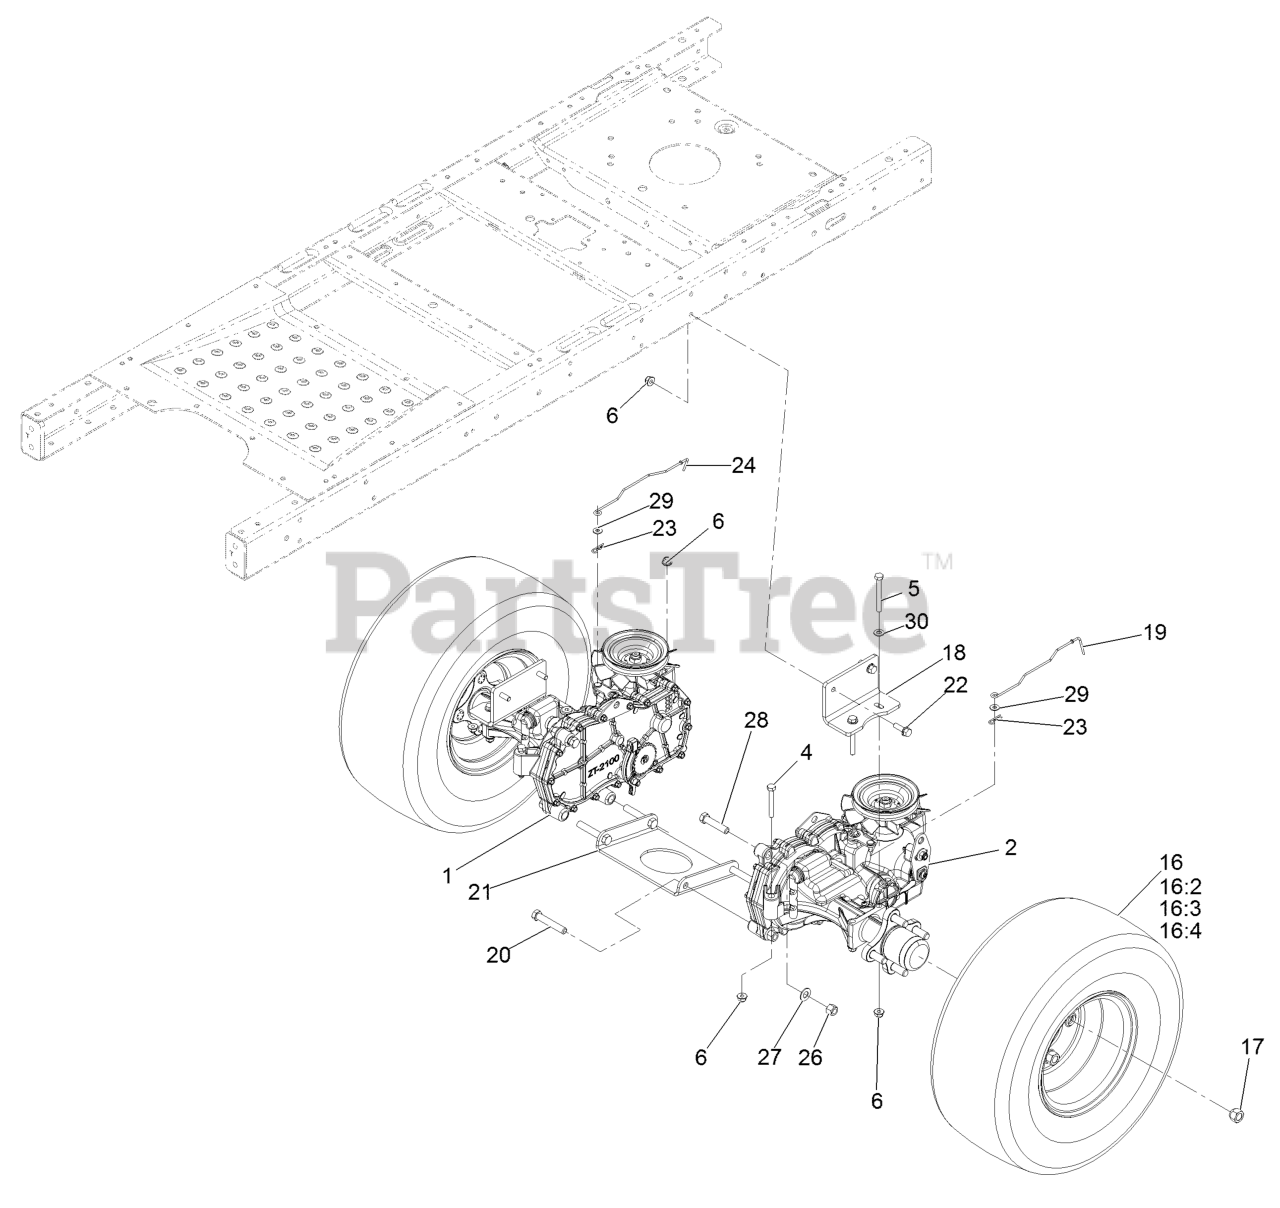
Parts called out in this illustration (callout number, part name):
1	RH HYDRO TRANSMISSION ASM
2	LH HYDRO TRANSMISSION ASM
4	SCREW-HH
5	SCREW-HH
6	NUT-HF, NI
16	2 PLY TIRE AND WHEEL ASM
16:2	TIRE-2 PLY
16:3	Stem-Valve
17	NUT-LUG
18	MOUNT-HYDRO
19	ROD-BYPASS, LH
20	SCREW-HH
21	PLATE-CROSS, HYDRO
22	SCREW-HHF
24	ROD-BYPASS, RH
26	NUT-LOCK, NI
27	WASHER-FLAT
28	SCREW-HH
30	WASHER-PLAIN
